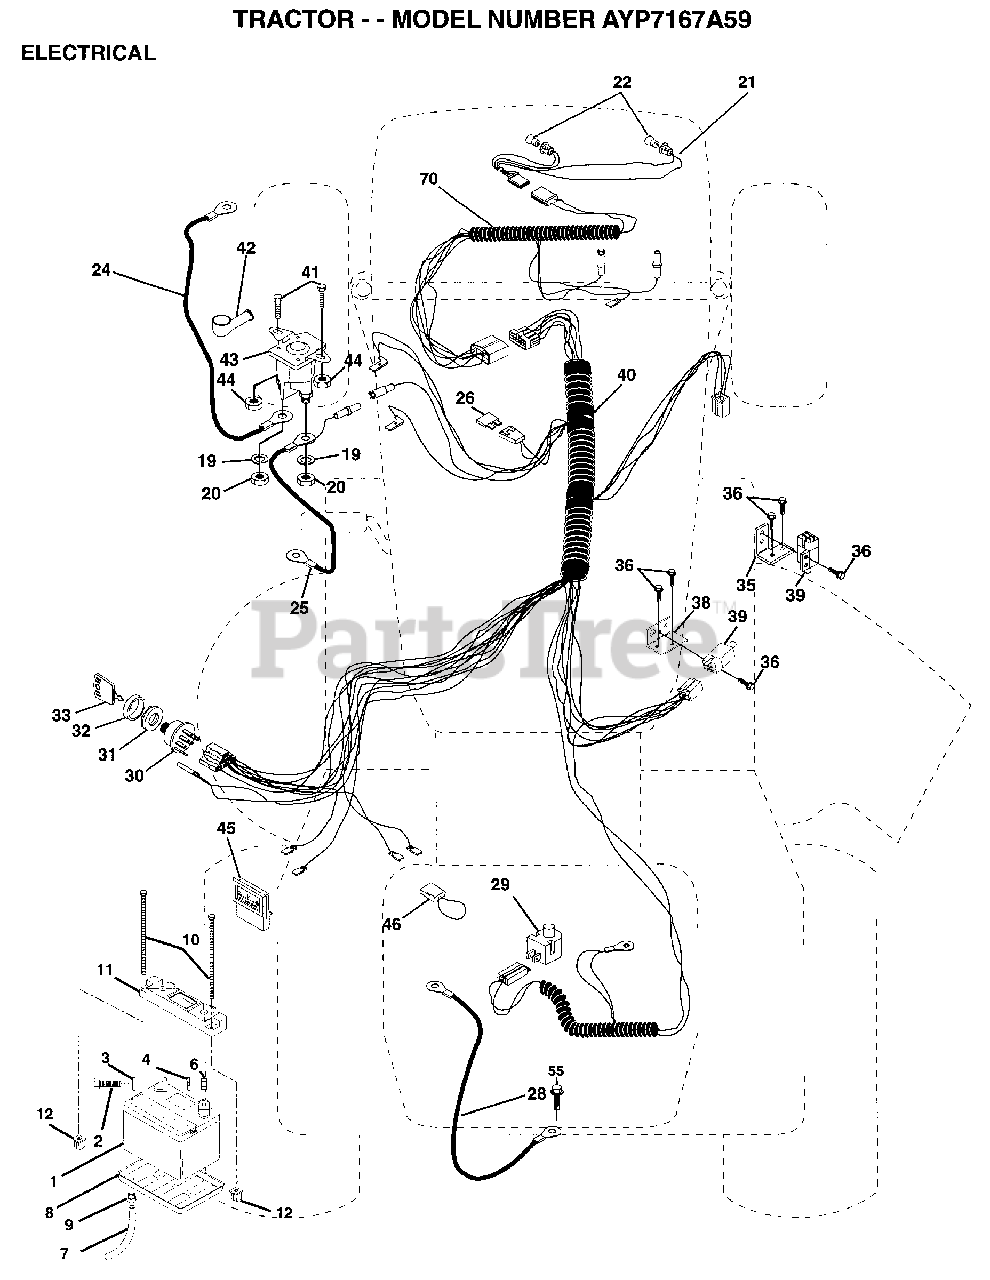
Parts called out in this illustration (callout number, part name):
2	BOLT LT
3	WASHER
4	LOCKWASHER
7	"DRAIN TU T, BATT"
8	"TRAY T, BATTERY"
9	HOSE CLAMP T
20	NUT
21	"HARNESS,LIGHT SOC"
22	HEADLAMP BULB
24	"CABLE T, BATTERY"
25	CABLE.6GA.22W/16W
26	FUSE HYT
28	CABLE.GRND.6GA.21
29	SWITCH SEAT
30	SWITCH IGN 4POS
31	NUT IGNITION
32	COVER KEY SWITCH
33	KEY
35	BRACKET LT
36	SCREW
38	BRACKET SWITCH IN
39	SWITCH INTERLOCKT
41	BOLT.HX.1/4-20
44	NUT
45	AMMETER
46	PROTECTION LOOP
55	SCREW LT
70	HARNESS.ENG.LT.
